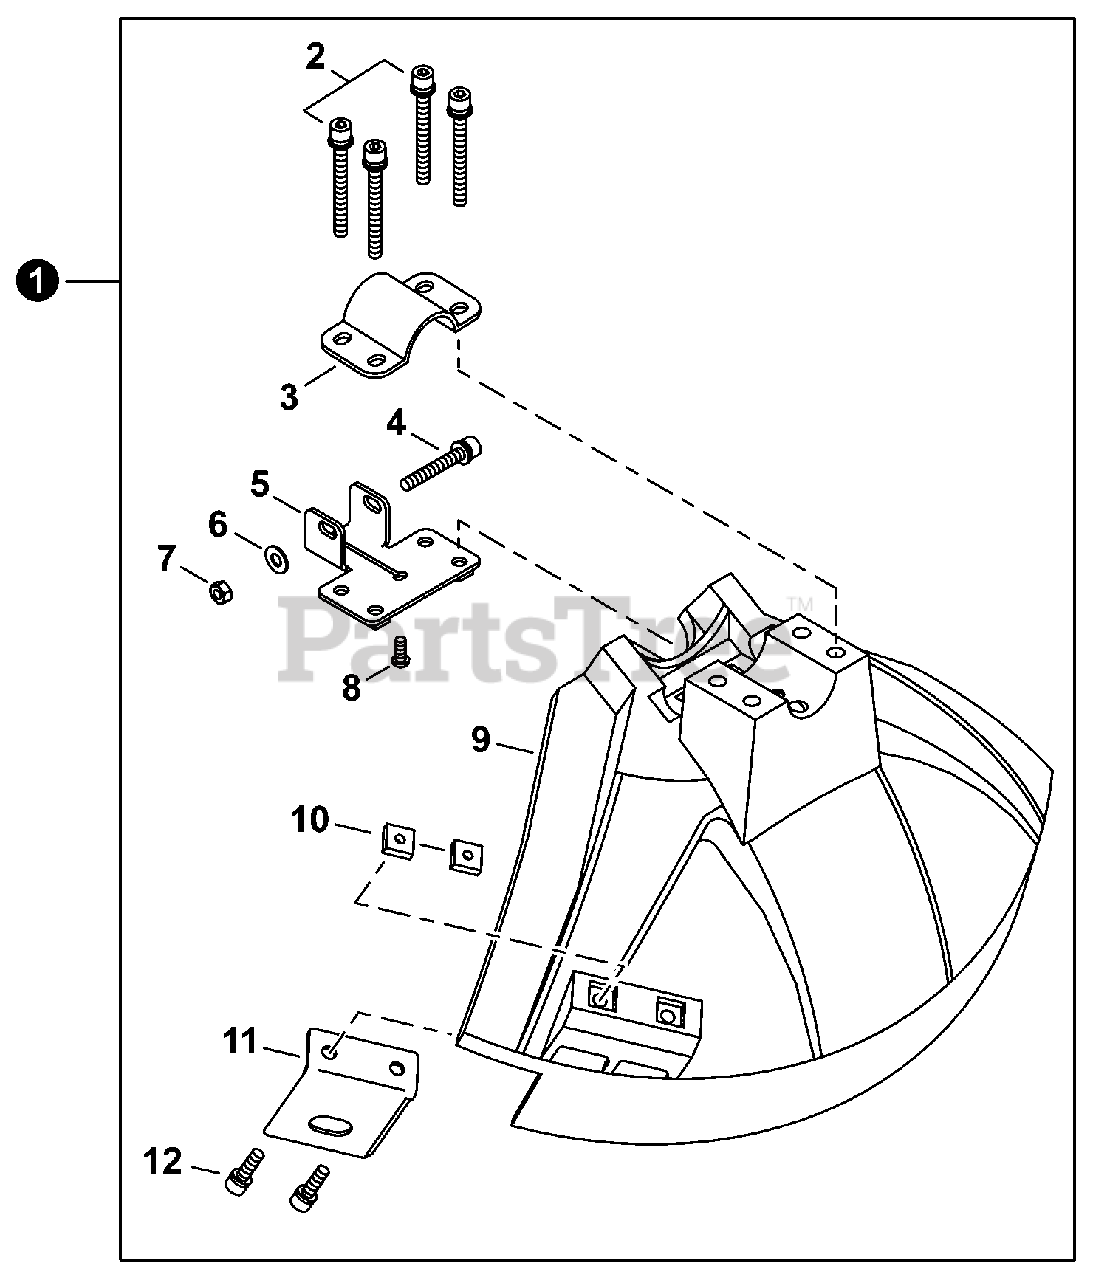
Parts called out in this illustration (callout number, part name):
1	DEBRIS SHIELD ASSY
2	BOLT M5×45
3	CLAMP, UPPER
4	BOLT M6×40
5	CLAMP, LOWER
6	WASHER 6.5×13×1
7	NUT, HEX M6
8	SCREW HILO 4×10
9	SHIELD, DEBRIS
10	NUT M5
11	CUTTER
12	BOLT 5×16
